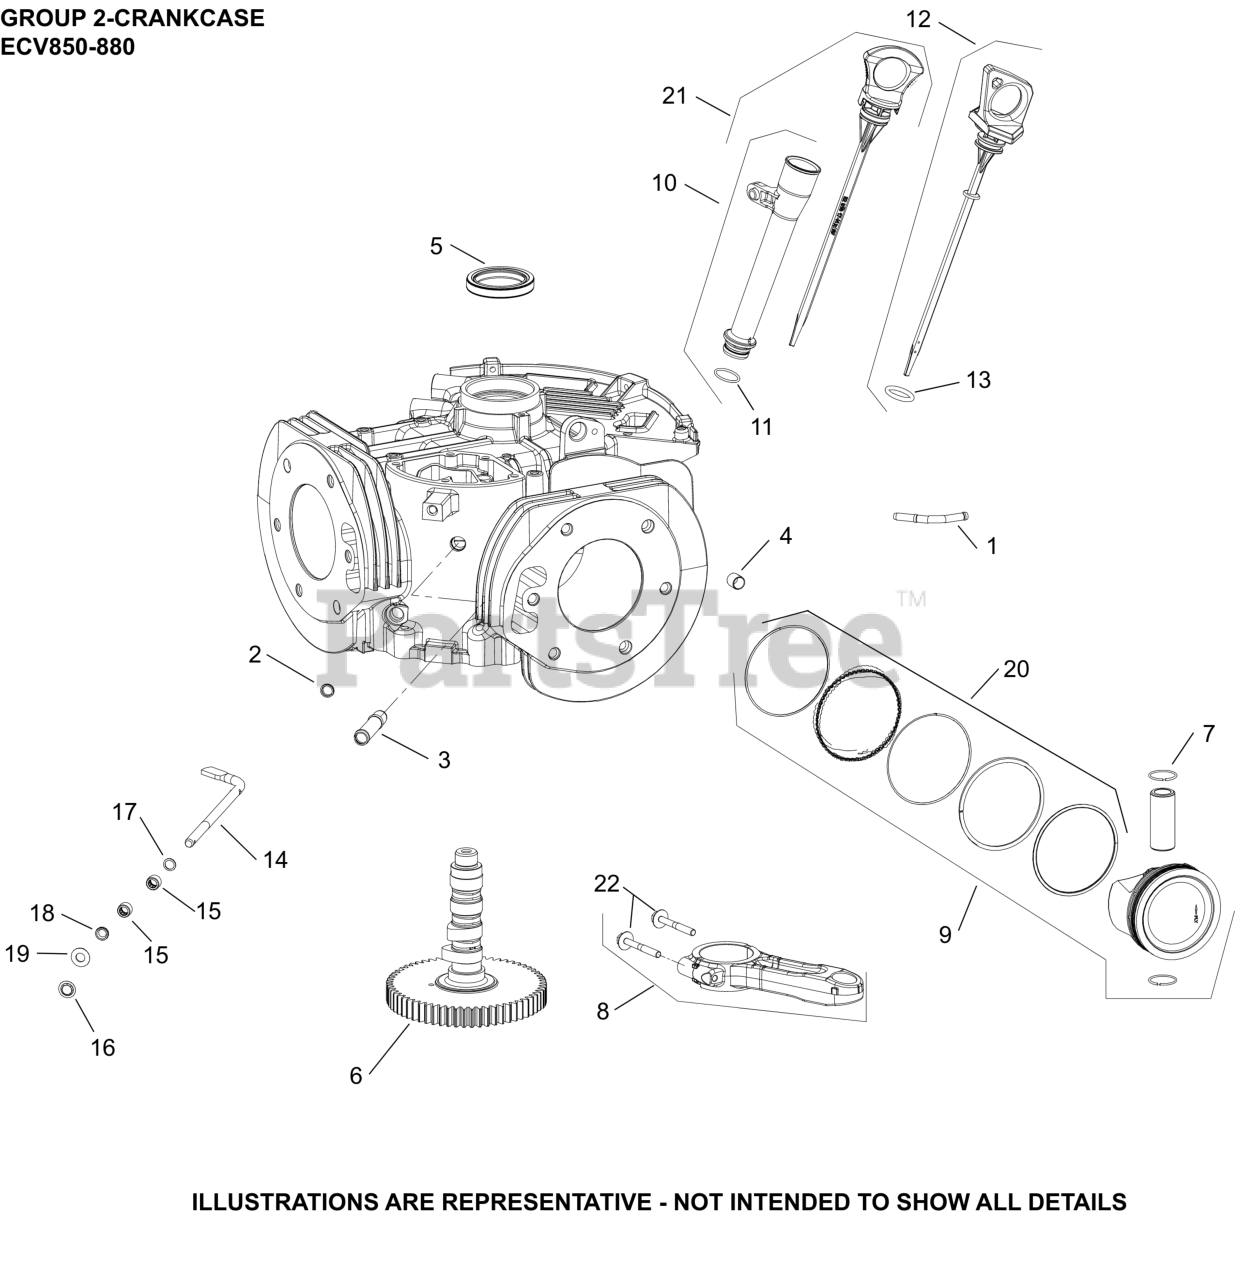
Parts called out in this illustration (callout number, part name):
3	FITTING, BREATHER HOSE
4	PIN, LOCATING
5	SEAL, OIL FW SIDE, BLACK
6	KIT, CAMSHAFT
7	RETAINER, PISTON PIN
8	ROD, CONNECTING ASSEMBLY
9	KIT, PISTON RINGS, PIN & CLIPS (STD)
9	KIT, PISTON RINGS, PIN & CLIPS (.25)
9	KIT, PISTON RINGS, PIN & CLIPS (.50)
14	SHAFT, GOVERNOR CROSS
15	BEARING, NEEDLE
16	RETAINER, RING
17	WASHER, FLAT 11/32"
18	SEAL, OIL
19	WASHER, FLAT 9 MM
20	KIT, RING SET (STD)
21	KIT, DIPSTICK AND TUBE WITH RINGS
22	KIT, ROD BOLTS
